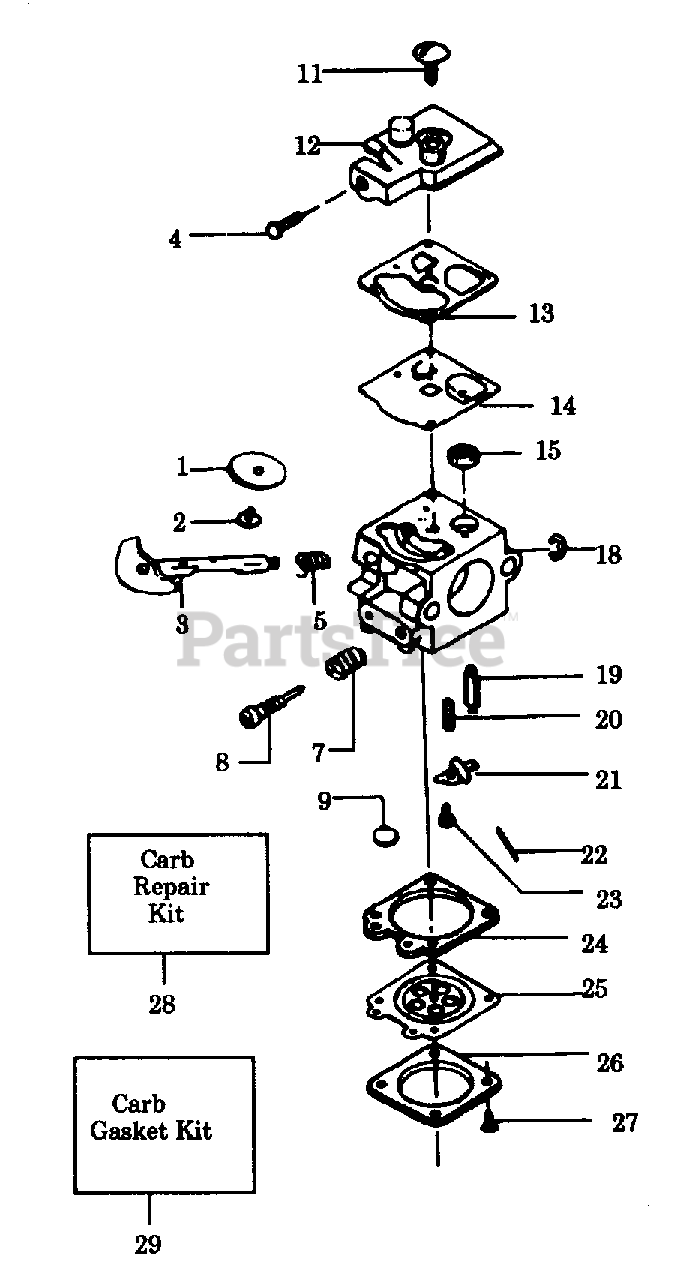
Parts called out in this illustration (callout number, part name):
1	Valve Throttle
2	Screw-Throttle Valve
3	Shaft Ass'y.-Throttle
4	Idle Speed Screw
5	Spring-Throttle Return
7	Spring-High Speed Mixture Needle
8	Needle-High Speed Mixture
9	Plug-5/16 Dia. Welch
11	Screw-Pump Cover
12	Cover-Fuel Pump
13	Gasket-Fuel Pump
14	Diaphragm-Fuel Pump
15	Screen-Fuel Inlet
18	Ring-Throttle Retainer
19	Valve-Inlet Needle
20	Spring-Metering Lever
21	Lever-Metering
22	Pin-Metering Lever
23	Screw-Metering Lever Pin
24	Gasket-Metering Diaphragm
25	Diaphragm-Metering
26	Cover-Metering Diaphragm
27	Screw Ass'y.-Metering Cover
28	Kit-Carb. Kwik Repair (Inc. 13,14,24,25)
29	Kit-Carb. Gasket/Diaphragm (Inc. 9,13,14, 19,20,21,22,23,24,25)
